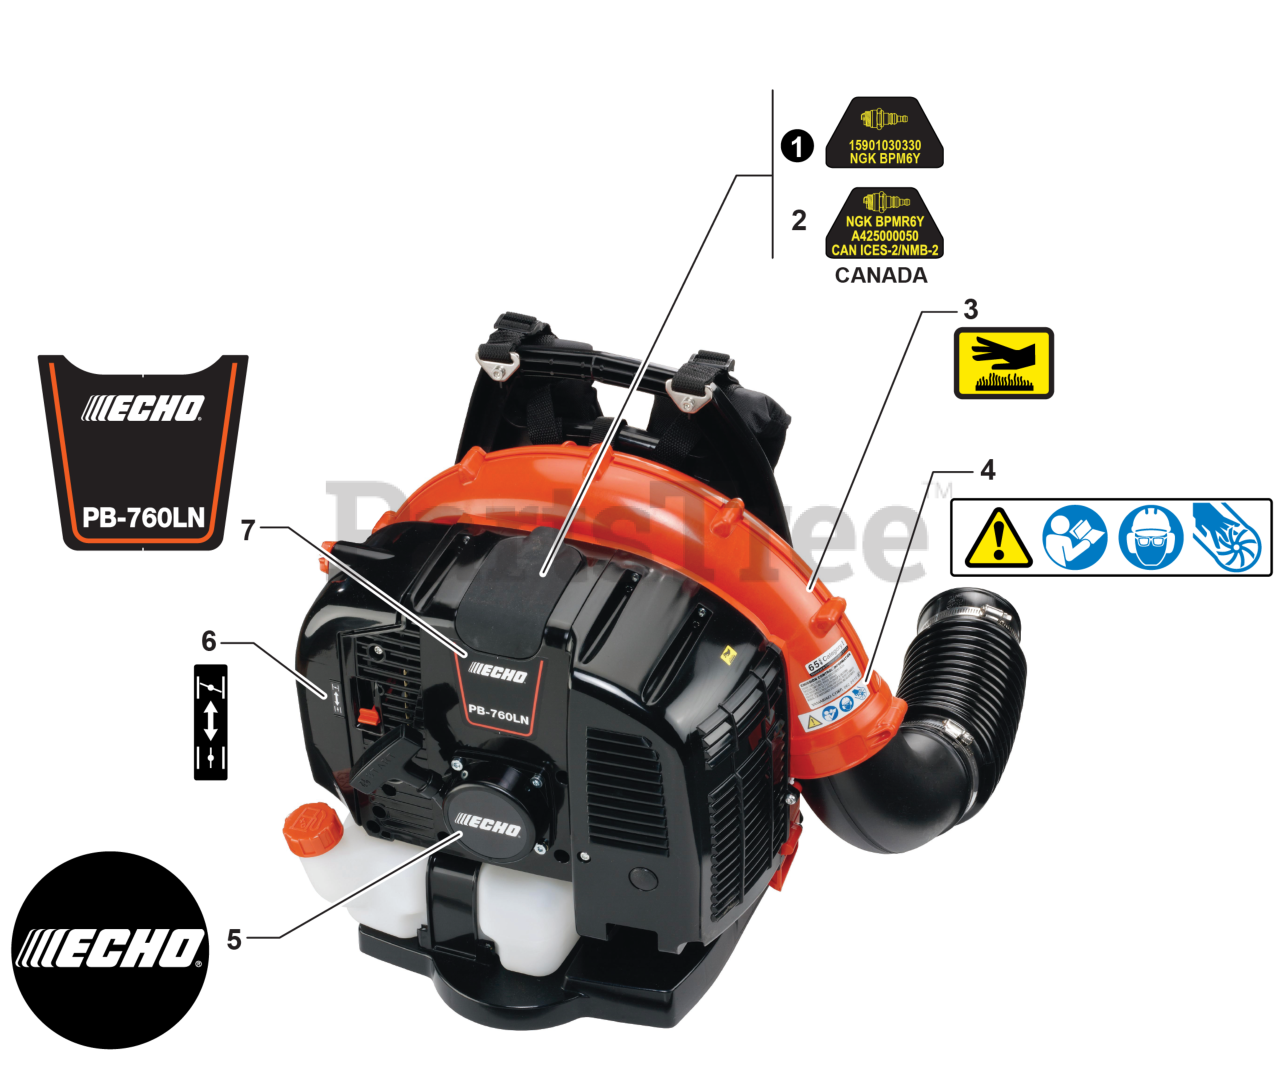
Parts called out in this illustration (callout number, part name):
1	LABEL - SPARK PLUG - BPM6Y
2	LABEL - SPARK PLUG - BPMR6Y
3	LABEL - CAUTION - HOT
4	LABEL - CAUTION - ISO
5	LABEL - STARTER - ECHO
6	LABEL - CHOKE
7	LABEL - MODEL PB-760LN
